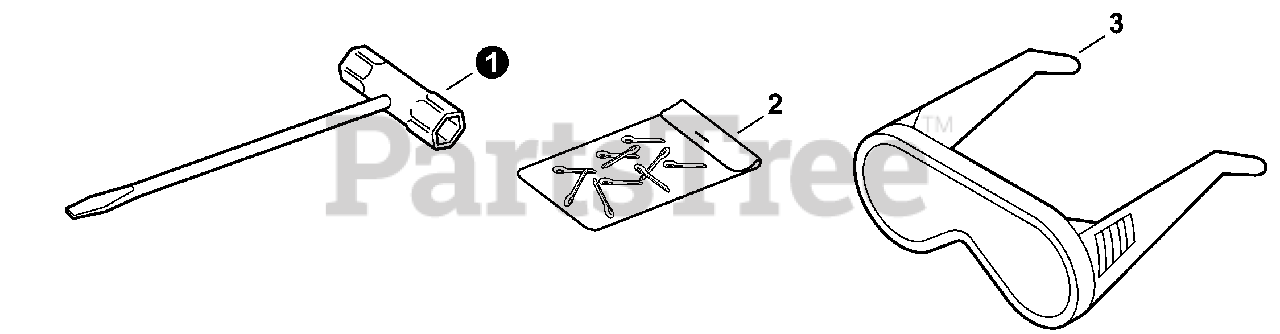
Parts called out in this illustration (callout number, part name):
1	T-WRENCH
2	PIN, COTTER 2×22
3	GLASSES, SAFETY
